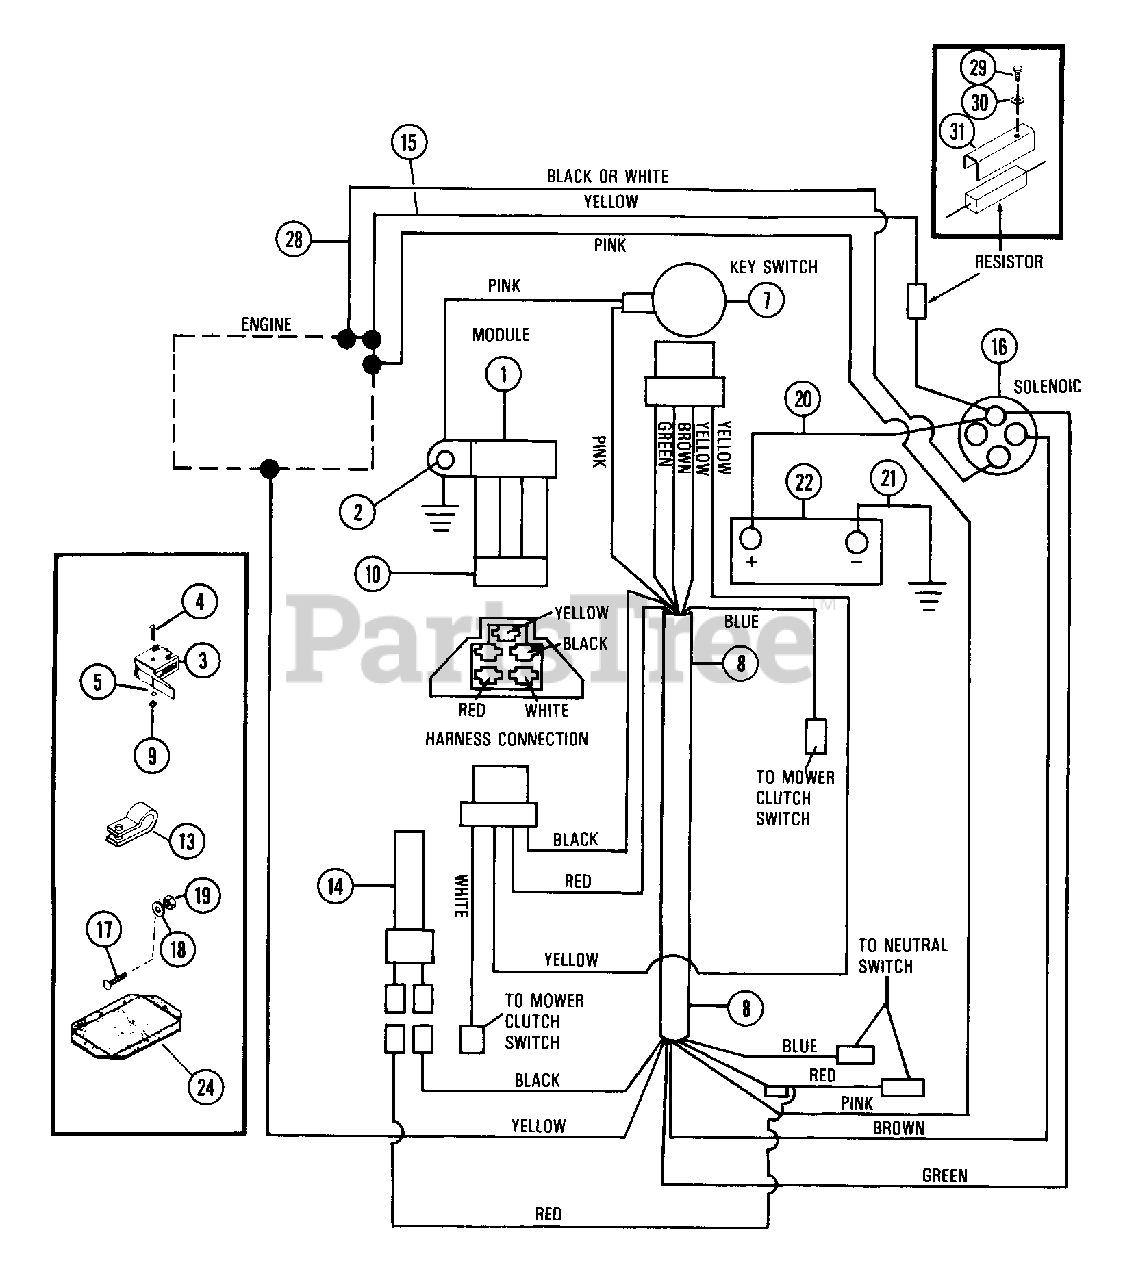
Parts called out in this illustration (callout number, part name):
1	MODULE
2	SCR-TAP 10-12X.50 CRPH PL A
3	SWITCH INTERLOCK
4	SCR-MCH 10-24X1.00 SLRH PL
5	WSHR-LK 10X.047 MED PL
6	NUT .625-32 ALUM
7	IGNITION SWITCH ASSEMBLY
8	WIRE HARNESS
9	NUT-HEX 10-24 PL
10	CONNECTOR
11	KEYS
12	WSHR-LK-INT .625X.045 PL
14	SWITCH SEAT
15	CHARGING WIRE
16	SOLENOID,STARTER SWITCH
17	BLT-RDHDSQNK .25-20X.50 SHT PL
18	WSHR-LK .250X.077 HVY PL
19	NUT-HEX .250-20 PL
20	GROUND CABLE .25X13.00X.31
21	GROUND CABLE .25X13.00X.31
22	BATTERY
23	BATTERY TRAY
24	RUBBER PAD
25	BATTERY STRAP
26	HOOK
27	SCR-TAP .312-18X.50 HWH PL TR
28	GROUND CABLE
